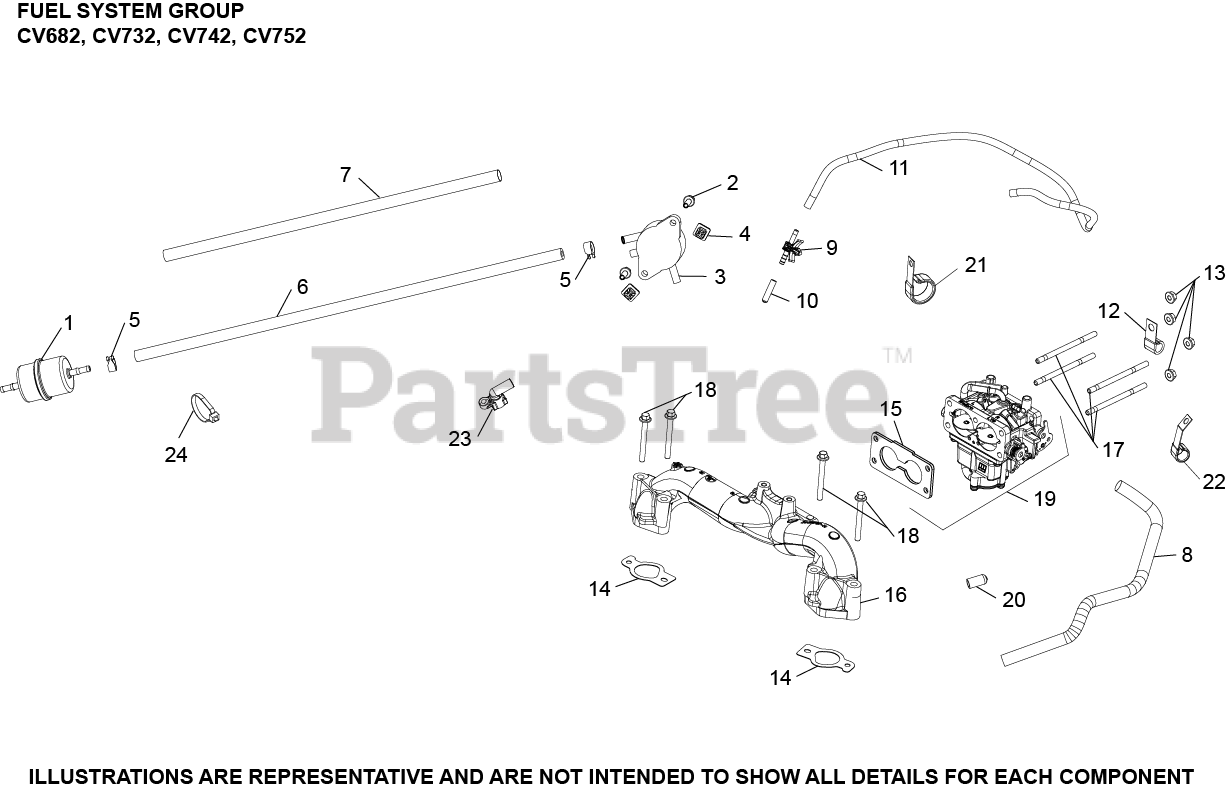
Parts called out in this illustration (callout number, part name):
1	FILTER, FUEL
2	SCREW, TAP M6X1.7X18
3	PUMP, FUEL
4	NUT, PLASTIC - BLACK
5	CLAMP, HOSE (KM)-USE 25 237 31-S
6	HOSE, FUEL LOW PERMEATION
8	SLEEVE, ANTI-ABRASION
12	CLIP, CABLE
13	NUT, FLG M6X1.0
14	GASKET, INTAKE MANIFOLD
15	GASKET, CARBURETOR
16	MANIFOLD, INTAKE (VERTICAL 2BBL)
17	STUD,M6X1.0X96
18	SCREW, FLG M6X1.0X55
19	KIT, CARBURETOR
23	FITTING, EVAP CONNECTOR
2407942-S	LINKAGE, THROTTLE
2451841-S	CARB SOLENOID LEAD
25086157-S	SCREW, HEX FLANGE HI-LO
X-22-11-S	WASHER, INT TOOTH LOCK 1/4"
